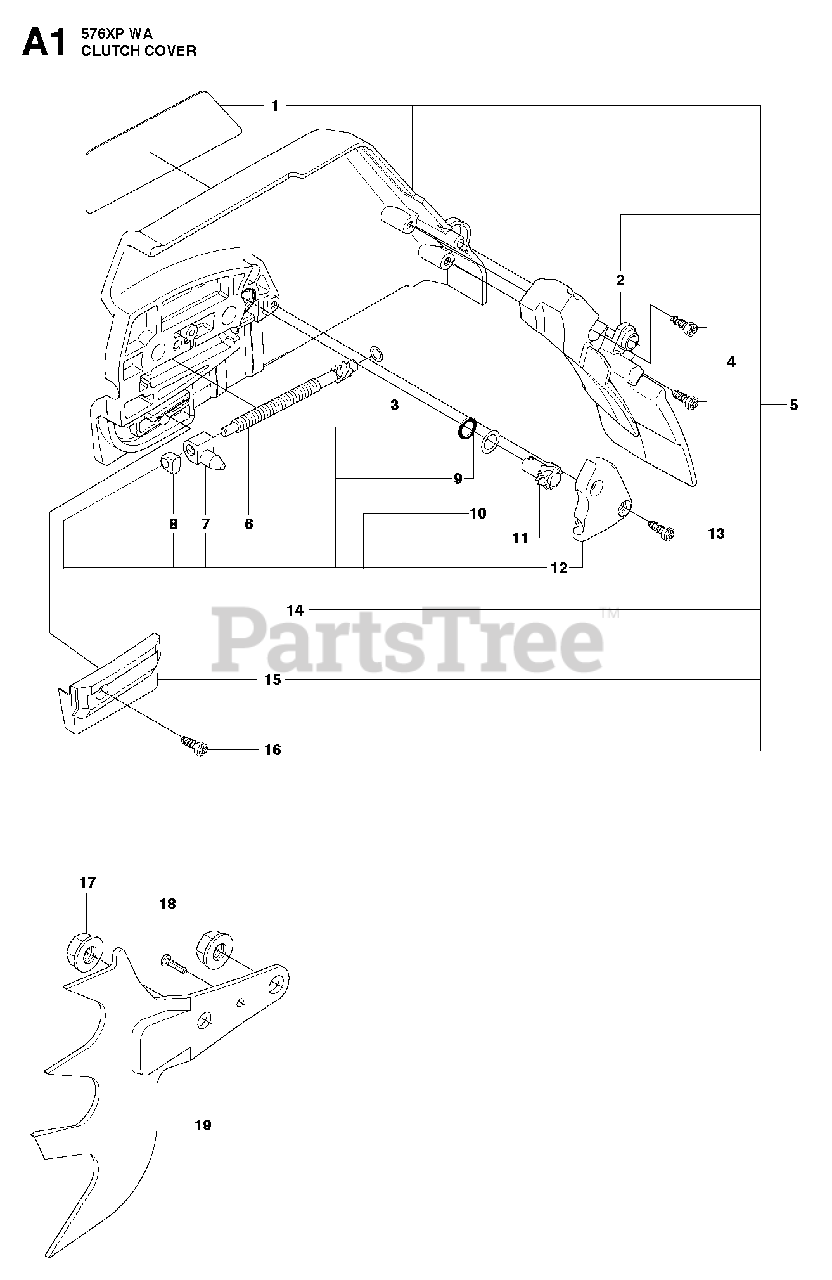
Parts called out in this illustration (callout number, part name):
2	PROTECTOR
3	WASHER
4	SCREW
5	CLUTCH COVER ASSY
6	WORM SCREW / ADJUSTER
7	PAWL
8	SLEEVE
9	O-RING
10	WASHER
11	RP ADJUSTER
12	COVER
13	SCREW
14	KIT-CHAIN TENSIONER
15	CHAIN GUIDE
16	SCREW
17	NUT M8 FLANGE
19	FELLING DOG
